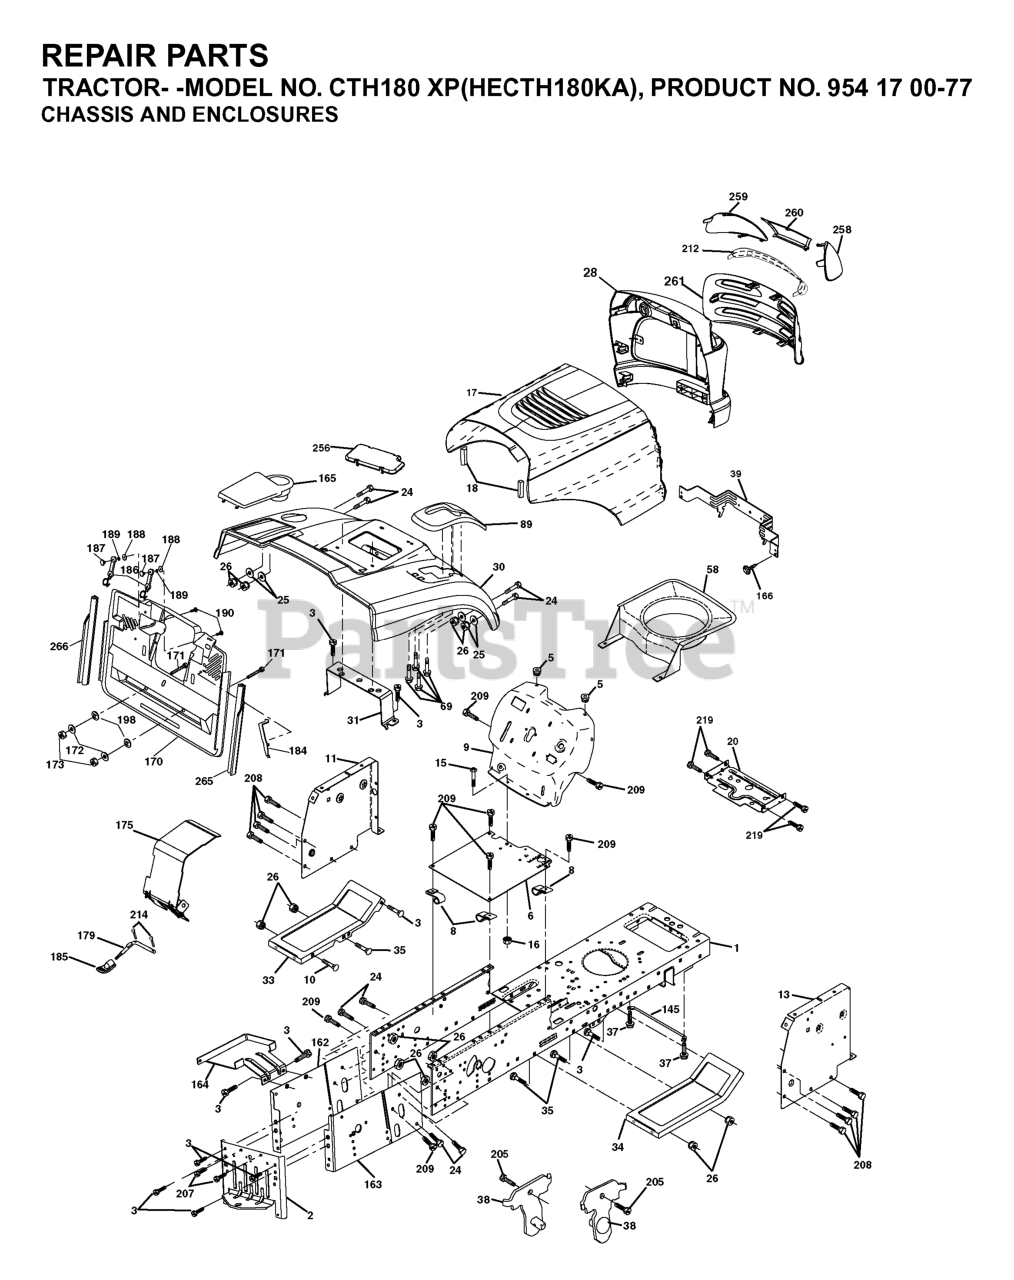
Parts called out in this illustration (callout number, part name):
2	DRAWBAR
3	SCREW 3/8-16X3/4
5	BUMPER.RUBBER.HOOD
6	PLATE
8	CLIP,INSULATOR
10	BOLT D
11	PANEL.DASH.LH.LTX
13	PANEL ASM, DASH RH
15	Screw, Machine, Truss Head 5/16-18 UNC x 3/4
16	NUT
17	HOOD
18	BUMPER.HOOD.LARGE.1.75"
20	PLATE MTG.BATTERY/FUEL TANK
25	WASHER
26	NUT
31	BRACKET SUPPORT FENDER
33	FOOTREST PNT LH
34	FOOTREST PNT RH
37	Screw 5/16-18 x 1/2 Hex, Self Tapping 5/16-18 x 1/2
38	BRACKET ASM PIVOT MOWER REAR
39	BRACKET PIVOT LASER
69	SCREW.HI-LO.CONSOLE
89	COVER.BATTERY.CRD.GREY
145	ROD PIVOT CHASSIS/HOOD
162	BRACKET
163	BRACKET EXTEN CHASSIS RH CRD
165	RP.COVER.BATTERY.CRD.GREY
166	SCREW
172	WASHER
184	BRACKET.ACTUATOR.BAGGER.SRD
186	LATCH ASSY
187	WELDNUT
189	LOCKWASHER #10
190	SCREW
207	SCREW, 5/16-18 X 1/2
208	SCREW 3/8-16X1/2
209	SCREW, 3/8-16X3/4
212	INSERT.LENS.REFLECTIVE
214	RETAINER M
219	SCREW
256	COVER FENDER CRD
258	LENS LH
259	LENS LH
260	COVER.LENS.HUSQ.LASER
265	SEALING
266	SEALING
